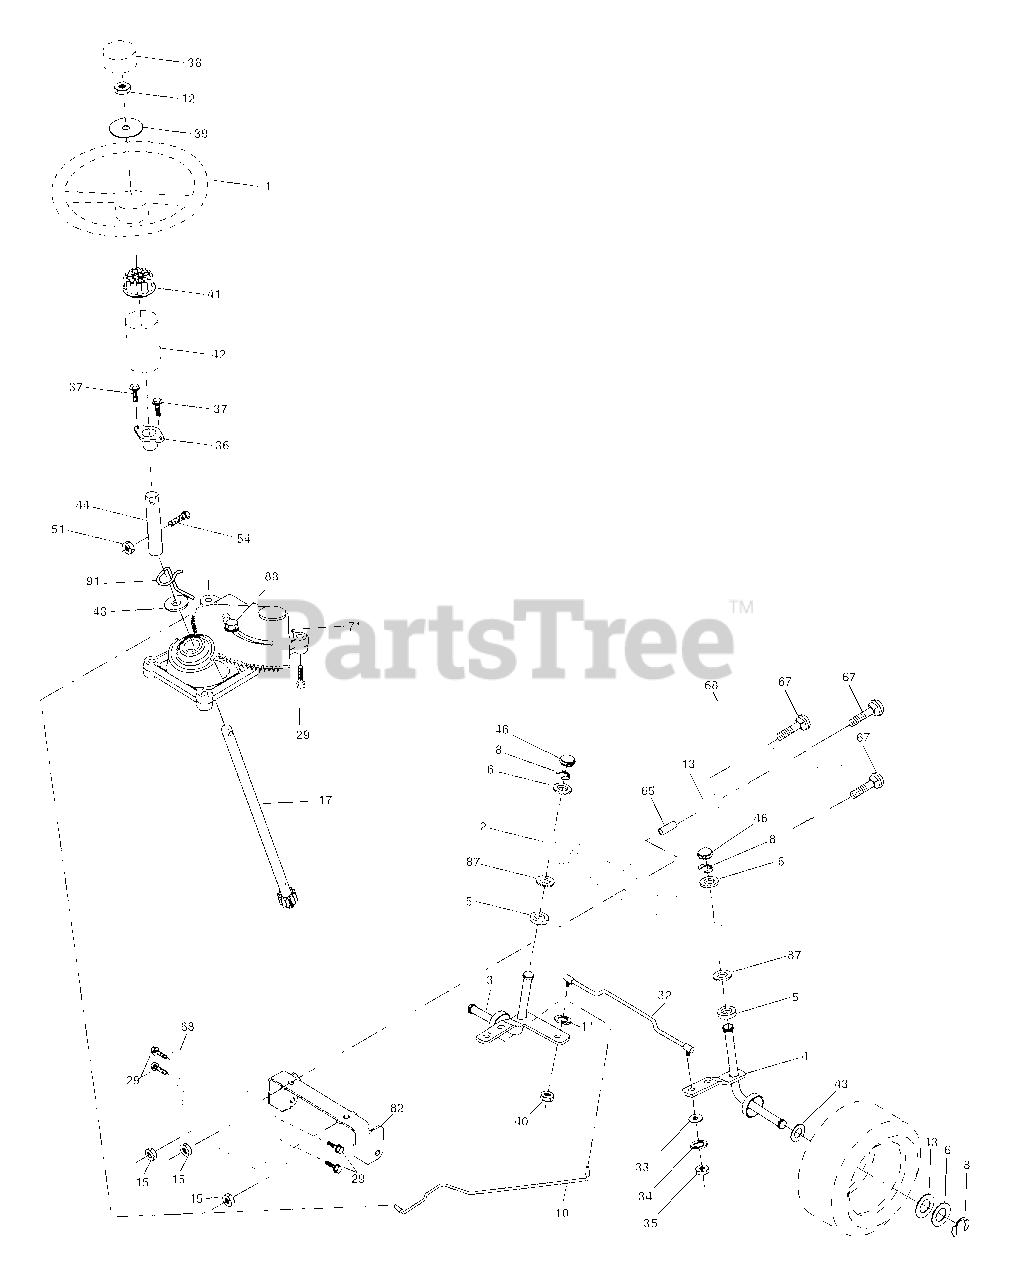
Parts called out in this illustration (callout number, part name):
1	Wheel Steering
2	Axle Asm Front
3	Spindle Asm Lh
4	Spindle Asm Rh
5	Bearing Race Thrust Harden
6	Washer 25/32 X 1 5/8 X 16ga
8	Ring Klip #t5304-75
10	Link Drag Extended
11	Lockwasher
12	Nut Hex Jam Toplock 1/2-20 Unf
13	Spacer Bearing Axle Front
15	Hex Flange Lock
17	Shaft Asm Strg
29	Screw 3/8-16x3/4
32	Rod Tie
33	Washer 11/32 x 3/4 x 16 Ga.
34	Washer lock 5/16
35	Nut Crownlock 5/16-24
36	Bushing Strg 5/8 Id Dash
37	Screw TT #10-32 x 5 x 3/8 Flange
38	Insert Cap Strg
39	Washer 9/16 ID x 1-1/2 OD 11 Gr
40	Locknut Center
41	Adaptor Wheel Strg
42	Boot Dash Steering
43	Washer 25/32 X 1 1/4 X 16 Ga
44	Extension Steering
46	Cap Spindle
51	Nut Crownlock 1/4-28
54	Bolt Hex 1/4-28unf x 1-1/4 Gr. 8
65	Spacer Brace Axle
67	Bolt Rdhd Sq 3/8-16 Unc x 2-3/4
68	Brace Axle
71	Steering Asm
82	Bracket Susp Chassis Front
87	Washer Flat
88	Bolt Shoulder 7/16-20
91	Clip Steering
